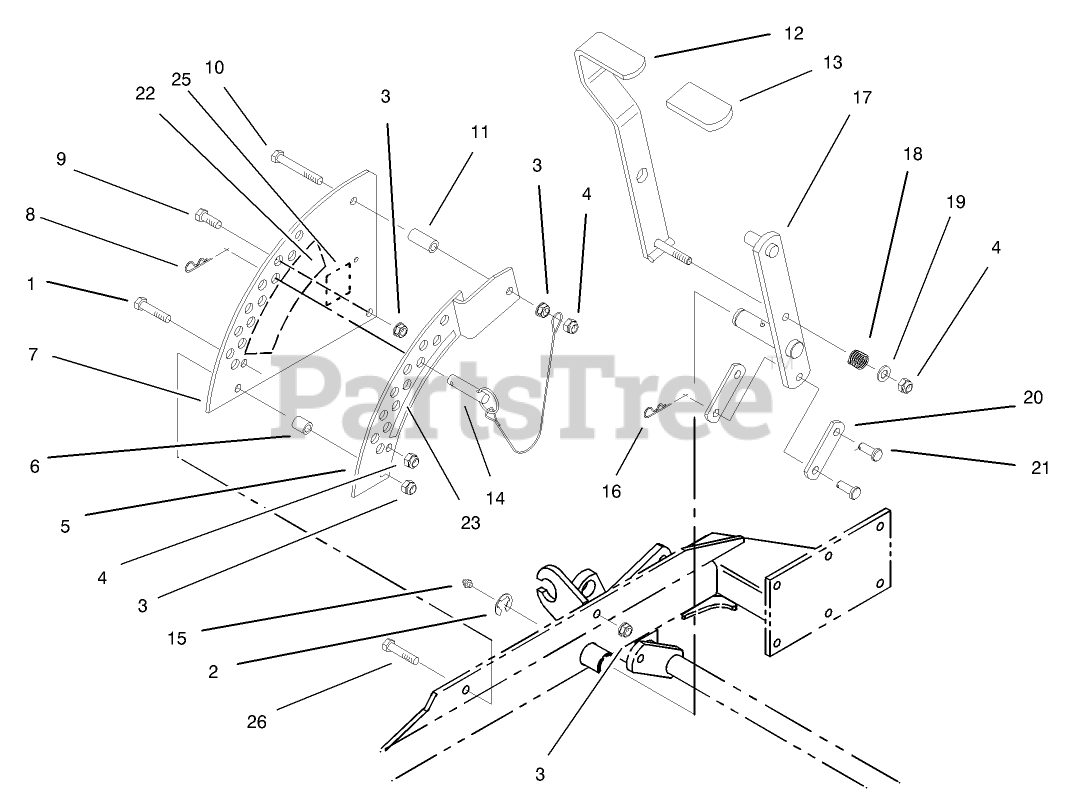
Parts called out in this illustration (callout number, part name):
1	SCREW-HH
2	RING-RETAINING, EXT
3	NUT-HHF, WHIZ
4	NUT-LOCK, NI
5	PLATE-LIFT, DECK
6	BUSHING-LEVER, LIFT
7	PLATE-LIFT, DECK
8	PIN-COTTER
9	SCREW-HH
10	SCREW-HH
11	BUSHING-LEVER, LIFT
12	HANDLE-LIFT
13	GRIP-LEVER, LIFT
14	PIN-HITCH (W/LANYARD)
15	FITTING-GREASE
16	PIN-COTTER
17	ARM-LIFT
18	SPRING-COMPRESSION
19	WASHER-FLAT
20	ARM-LIFT, DECK
21	PIN-CLEVIS
22	DECAL-DECK HEIGHT, OUTER
23	DECAL-DECK HEIGHT, INNER
25	DECAL-NOISE
26	SCREW-HH
